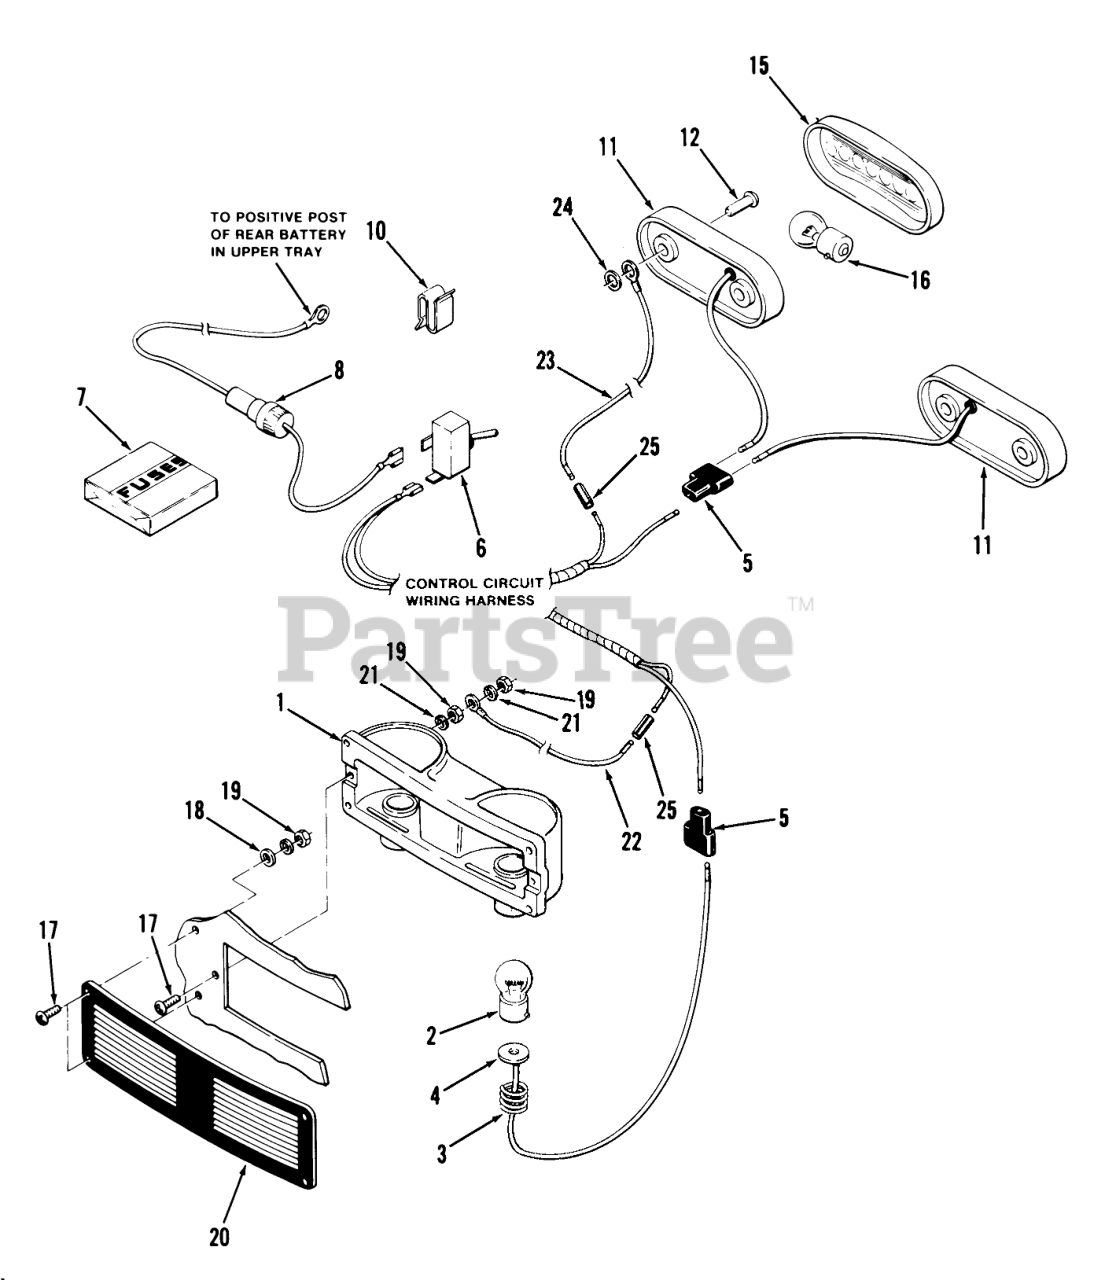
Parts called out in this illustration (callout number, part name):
1	ASSY REFLECTOR HOUSI
2	BULB
3	SPRING
4	WIRE ASSY
5	CONNECTOR 3 WIRE
6	SWITCH-LIGHTS
8	Tine Bolt
10	Clip
11	BASE-TAIL LIGHT
12	Pop Rivet
15	Lens-Taillight
16	Bulb
17	SCREW #6-32 SELF TAP
18	WASHER
19	Nut #6-32
20	LENS-HEADLIGHT
21	Lockwasher #6
22	ASSEMBLY-WIRE
23	Ground Wire-Taillights
24	WASHER
25	CONNECTOR 2 WIRE
